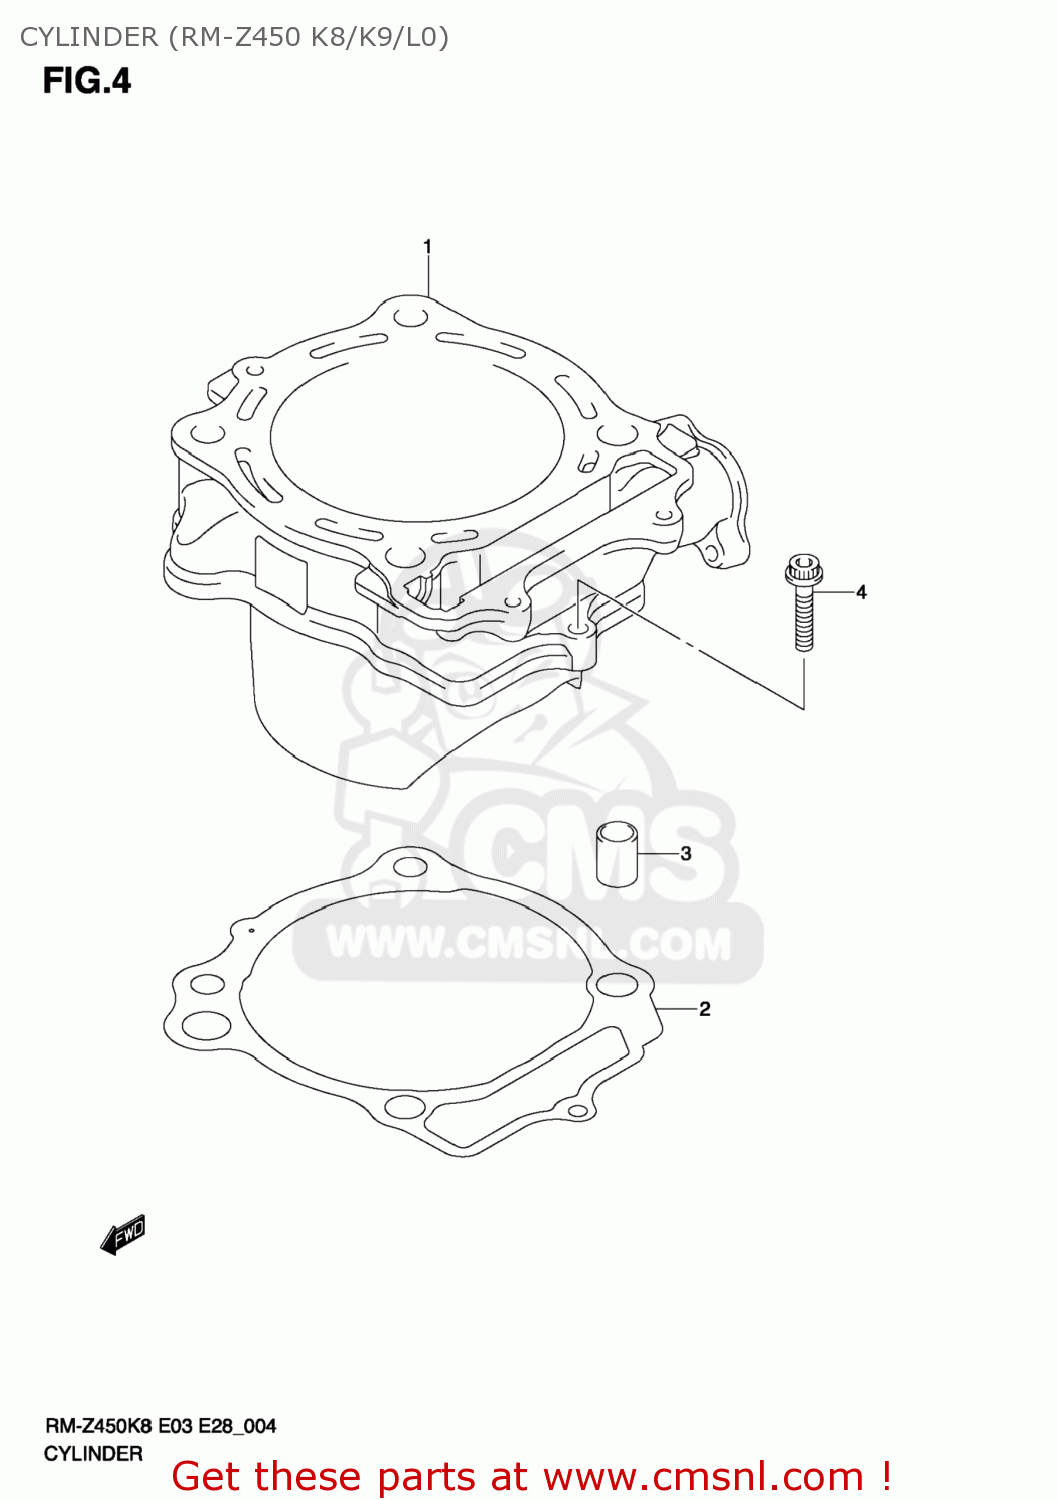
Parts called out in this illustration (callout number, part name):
1	CYLINDER
2	GASKET,CYLINDER (NAS)
3	PIN
4	BOLT
